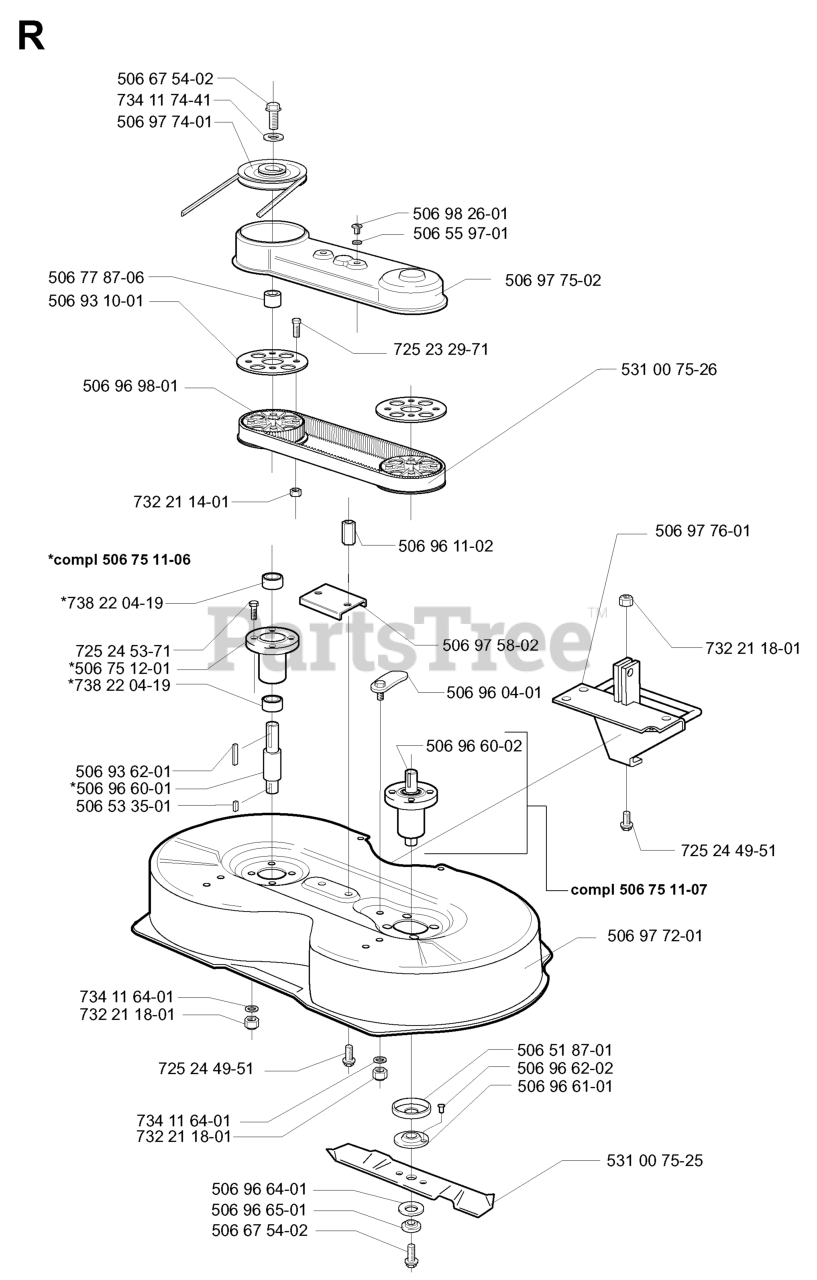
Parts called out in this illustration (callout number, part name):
1	FILTER AIRBOX
3	CHOKE LEVER
4	PURGE BULB ZAMA
5	KIT GASKET 28CC
6	CARB ADAPTOR
7	KIT GASKET 28CC
8	BOLT CARB ADAPTOR
9	Accy - Spark Plug (RCJ6-Y)
10	KIT GASKET 28CC
11	KIT GASKET 28CC
12	WASHER FLAT
13	ASSY STARTER CUP
14	COUPLING-STARTER
15	FUEL PICK-UP ASSY
16	KIT-LINE(FUEL)
17	FUEL LINE FITTING
18	ASSY-CAP W/RETAINER
19	KIT GASKET 28CC
20	ISOLATOR FUEL TANK
21	KIT FUEL TANK HVA
22	REAR SHROUD
25	STARTER HANDLE GRAY
26	SCREW M5-0.8X30MM
27	STARTER HOUSING
28	%KIT STARTER SPRING
29	KIT STARTER PULLEY
31	ASSY-STARTER HSG.
32	BOLT MUFFLER
33	SCREW-6-19X5/16PLAST PA
34	SHIELD HEAT
35	SCREW M4 X 1.75 PT 16MM
36	GUARD-MUFFLER
37	KIT SPARK ARRESTOR SCREEN
38	KIT MUFFLER LE28
39	KIT GASKET 28CC
40	SCREW-M5-0.8 X 25MM(TAP)
41	IGNITION MODULE MB45
42	ASSY MODULE LEAD WIRE
43	SCREW M4 X .70 TT 16MM
44	WASHER CLUTCH
45	WASHER-CLUTCH
48	LOCKNUT-HEX 10-24
49	SCREW M4 X .70 TT 16MM
50	FAN HSG ASSY
51	ASSY-CLUTCH DRUM
52	%KIT CLUTCH ASSY
53	SPACER FLYWHEEL
55	CRANKCASE CAST LE28
56	BEARING RADIAL BALL (6201)
57	ASSY CRANKSHAFT FORGED ROD
58	WRIST PIN RET.
59	RING PISTON
60	KIT PISTON & CYLINDER
61	KIT GASKET 28CC
62	SCREW-M5-0.8 X 25MM(TAP)
63	CARBURETOR KIT W38
64	RP_AIR BOX
65	COVER-AIR BOX
66	KNOB ASSY AIRBOX COVER
67	KIT GASKET 28CC
